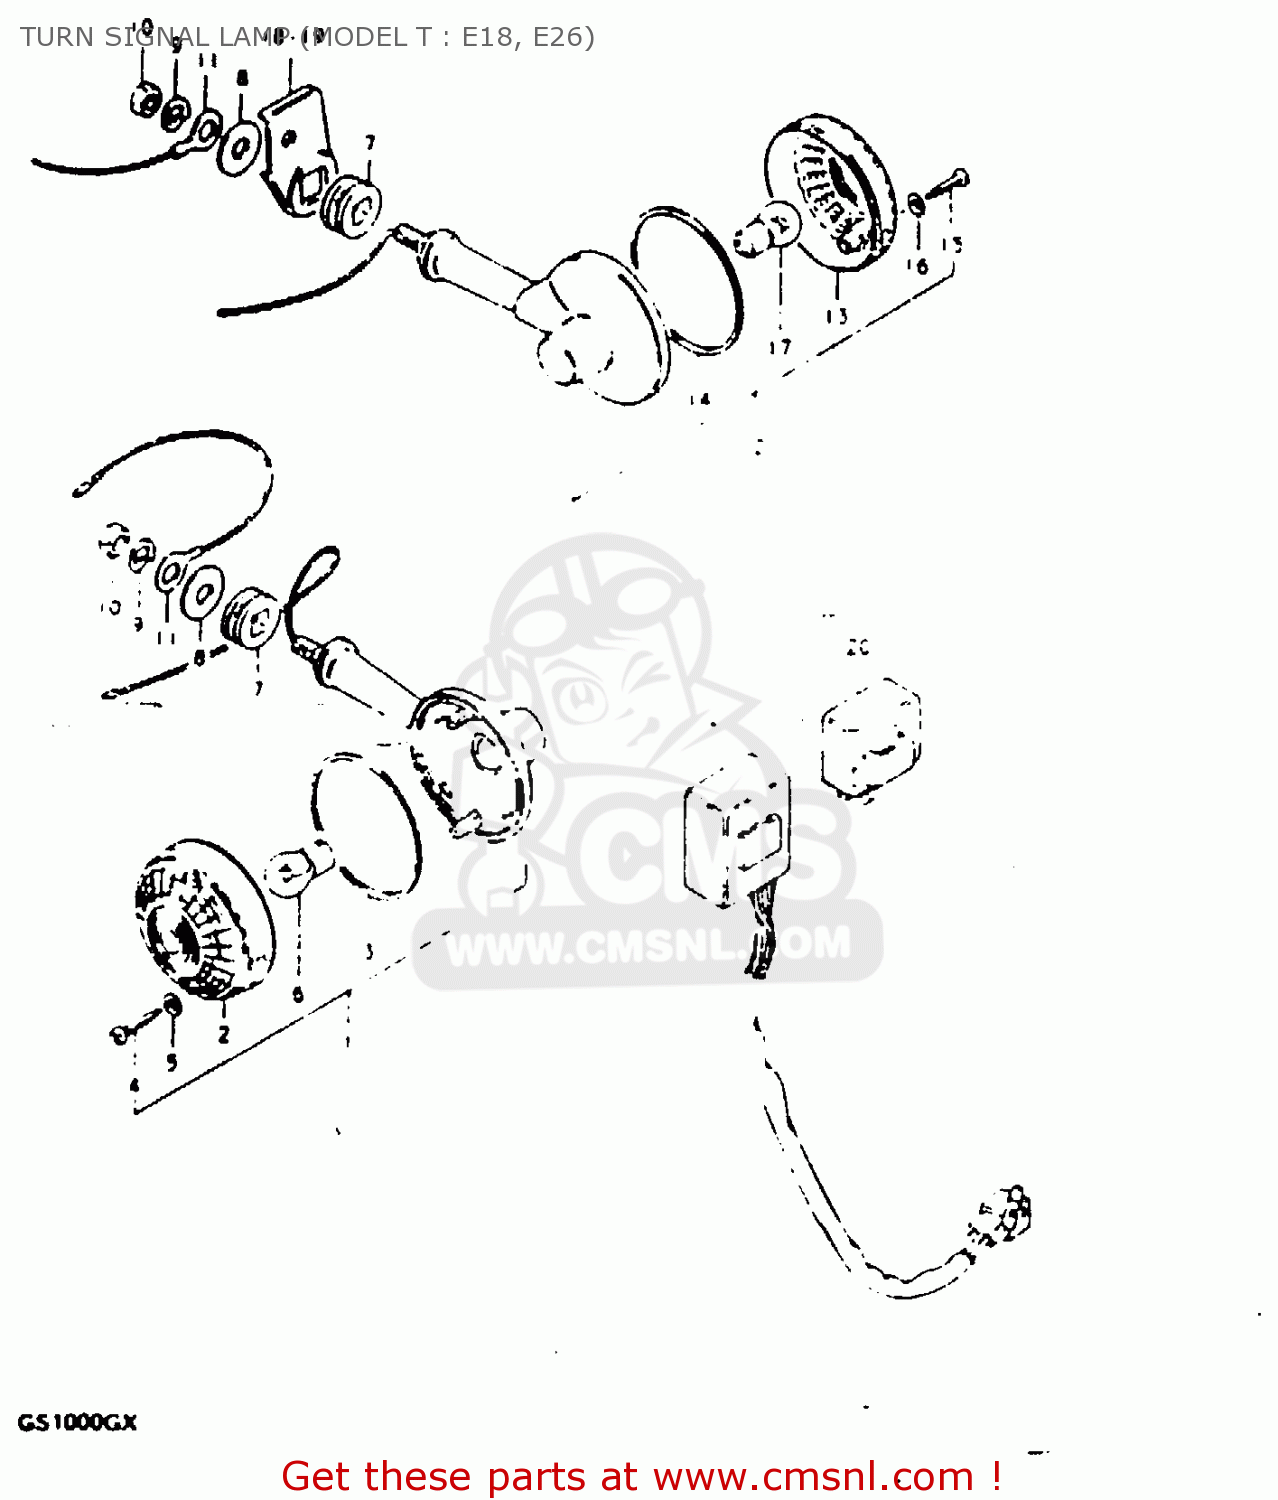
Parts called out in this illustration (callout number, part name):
1	LAMP, REAR TURN SIGNAL
2	LENS
3	GASKET (NAS)
4	SCREW (4X30)
5	GASKET (NAS)
6	BULB(12V21W)
7	CUSHION
8	WASHER (10.5X30X2.3)
9	LOCK WASHER
10	NUT
11	LEAD WIRE,EARTH
12	LAMP, REAR TURN SIGNAL
13	LENS
14	GASKET (NAS)
15	SCREW (4X30)
16	GASKET (NAS)
17	BULB(12V21W)
18	BRACKET,RR TURNSIGNAL LAMP,R
19	BRACKET,RR TURNSIGNAL LAMP,L
20	RELAY ASSY,TURNSIGNAL
21	UNIT,TURN SIGNAL CONTROL
